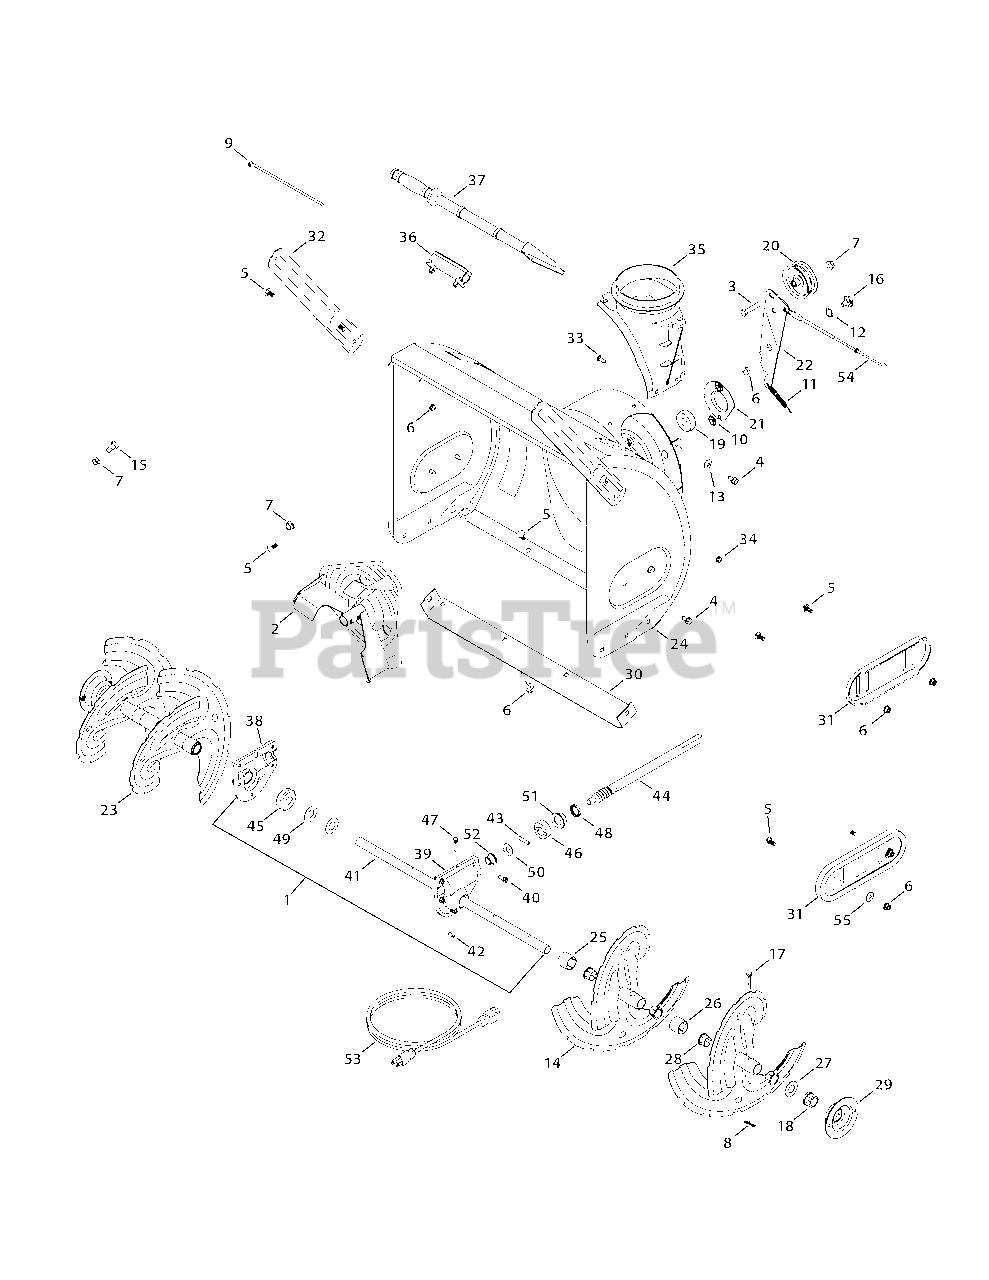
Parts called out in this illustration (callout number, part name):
1	Auger Gearbox, includes 38-52
2	Impeller Assembly, 12" Dia.
3	Hex Head Screw, 3/8-16 x 1.75
4	Screw, 5/16-18 x .750
5	Screw, Carriage, 5/16-18 x 1.00
6	Nut, Flange lock, 5/16-18
7	Nut, Flange lock, 3/8-16
8	Bow-Tie Cotter Pin
9	Cable Tie, 7"
10	Nut, Push-on, .25 Dia.
11	Extension Spring, .38 x 4.59
12	Washer, Wave, .625 x .885
13	Washer, Bell, .340 x .872
14	Spiral Assembly, LH
15	Bolt, Shoulder, .496 x .336 x 3/8-16
16	Screw, Shoulder, .625 x .17 x 3/8-16
17	Shear Pin, .25 x 1.50
18	Bearing, Hex Flange, .75
19	Bearing, Ball, .75 x 1.85
20	Pulley, Idler, Flat, 2.75
21	Bearing, 1.85 ID
22	Auger Idler Bracket
23	Spiral Assembly, RH
24	Auger Housing Assembly
25	Spacer, 1.25 x .75 x 1.00
26	Spacer, 1.25 x .75 x 2.00
27	Washer, Flat, .76 x 1.49
28	Bushing, Flange, .800 x .910
29	Bearing Housing, 1" Hex
30	Shave Plate, 2.25 x 29.66
31	Polymer Slide Shoe
31	Polymer Reversible Shoe Kit
31	Slide Shoe - Deluxe
32	Blade Guide
33	Screw, Carriage, 1/4-20 x .75
34	Nut, Flange lock, 1/4-20
35	Chute Adapter
36	Clean-Out Tool Mount
37	Clean-Out Tool
38	Reducer, RH
39	Reducer, LH
40	Screw, 1/4-20 x 0.750
41	Auger Axle, 30"
42	Key, Hi-Pro, 3/16 x 5/8
43	Dowel Pin, .25 x 1.25
44	Worm Shaft, .75
45	Gear Worm, 20T
46	Collar Thrust, .756 x .600
47	Plug, 1/4 x .437
48	Oil Seal, .75 x 1.131 x .188
49	Washer, Flat, .760 x 1.50
50	Washer, Flat, .51 x 1.12
51	Bearing, Flange, .75 x 1.00 x .59
52	Bearing, Flange, .50 x .75 x .59
53	Extension Cord, 110V
54	Auger Drive Clutch Cable
55	Washer, Flat, .349 x .879 x .063
